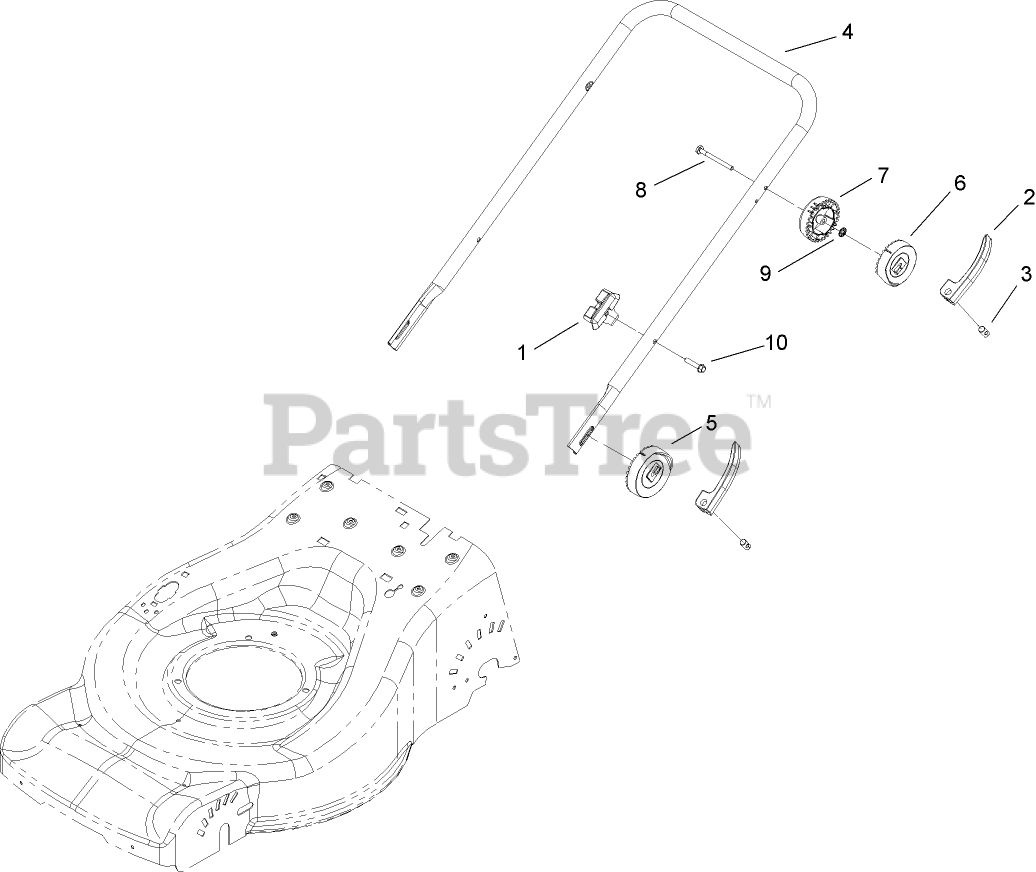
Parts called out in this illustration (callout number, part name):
1	ANCHOR-BAG
2	LEVER-LOCKING, HANDLE
3	PIVOT-PIN, THREADED
4	HANDLE-HOOP, LOWER
5	ADAPTER-RATCHET, LOWER
6	ADAPTER-RATCHET, MIDPOINT
7	ADAPTER-CLAMP, MIDPOINT
8	SCREW-HH
9	WASHER-STARLOCK, PUSH
10	SCREW-HWH
